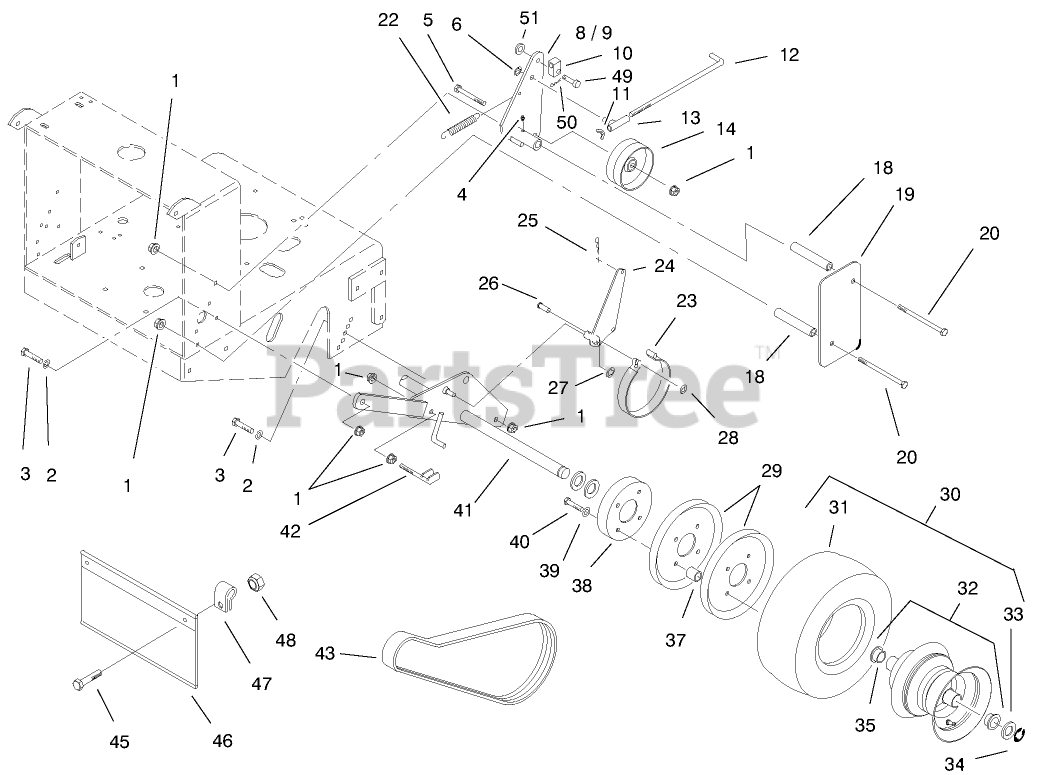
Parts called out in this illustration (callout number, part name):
1	NUT-FLANGE
2	Washer
3	SCREW-HH
4	FITTING-STRAIGHT
5	SCREW-HH
6	Ring
8	Idler Arm ASM LH
9	Idler Arm ASM RH
10	FITTING-ROD
11	Wingnut
12	Brake Rod
13	Swivel
14	Idler-Wheel Drive
18	Idler
19	Shield
20	SCREW-HH
22	Spring-Extension
23	Band-Brake
24	Brake Arm ASM
25	PIN-COTTER
26	Pin
27	Ring-Snap
28	Nut
29	Sheave
30	WHEEL AND TIRE ASM
31	Tire
32	Assembly-Wheel
33	Spacer
33	Spacer-18 GA
34	Ring,Snap E
35	Bearing
37	Spacer
38	Drum-Brake
39	WASHER-LOCK
40	SCREW-HH
41	Axle ASM
42	Scraper
43	Belt-Drive
45	SCREW-HH
46	Shield-Trailing
47	CLAMP-R
48	NUT-LOCK NI
49	PIN-CLEVIS
50	PIN-COTTER
51	WASHER-PLAIN
